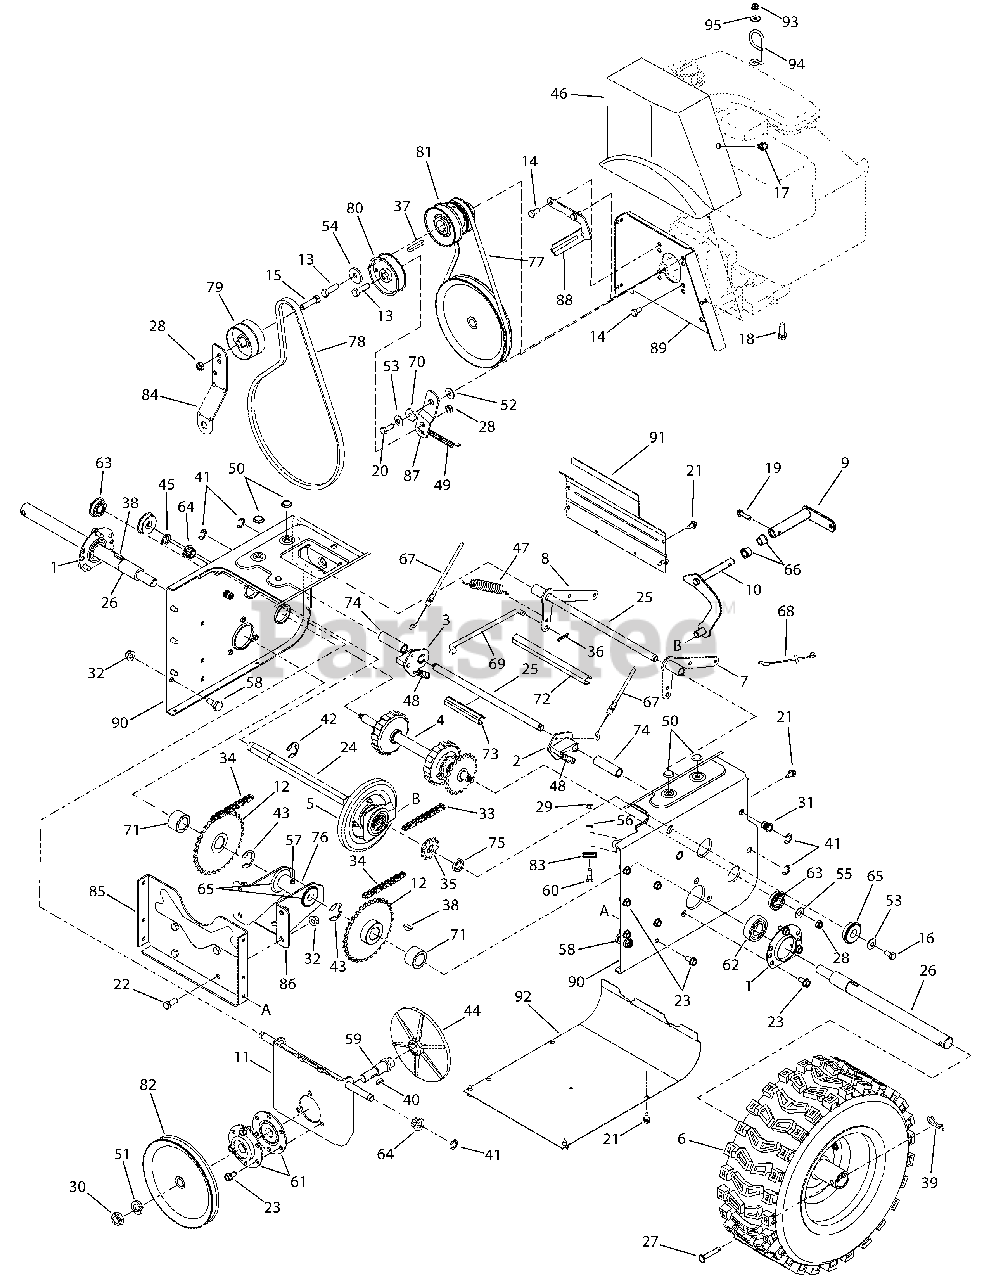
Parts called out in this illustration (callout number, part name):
1	Housing, Bearing
2	Dogg, Steering Drive, LH
3	Dogg, Steering Drive, RH
4	Shaft Assembly, Steering
5	Assembly, Friction Wheel
10	Rod Assembly, Shift
12	Sprocket, 32T
13	Screw, Hex Cap, 3/8-24 x 1.25 Gr8
14	Screw, Hex Cap, 5/16-24 x .625 Gr5
15	Screw, 3/8-24 x 1.50
16	Screw, Hex Cap Lock, 5/16-18 x .625 Gr5
17	Screw, Hex Tapp, 5/16-18 x .5
18	Screw, Hex Sems Tapp, 3/8-16 x 1.0
19	Screw, Hex, 1/4-20 x 1.00
20	Screw, Hex Lock, 5/16-24 x .875 Gr8
21	Screw, Hex Wash.
22	Screw, Hex Cap, 3/8-16
23	TT Screw, 5/16-18 x .750
24	Shaft, Hex Drive
25	Shaft, Actuator
26	Axle, Wheel
27	Pin, Clevis
28	Nut, Hex Insert Jam Lock
29	Nut, Hex, 1/4-28 GR5
30	Nut, Hx Insert Jam Lk
31	Nut, Insert 3/8-16
32	Nut, Hx Flnge Insert Lk
33	Chain, Endless, #41 x 36L
34	Chain, #420 x 40L
35	Sprocket, #41 x 10T
36	Pin, Internal Cotter
37	Key, Square, 1/4 x 1.5
38	Key, Woodruff
39	Pin, Internal Cotter
40	Key, Hi-Pro, 3/16 x 5/8
41	E-Ring
42	Ring, Retaining
43	Ring, Retainer
44	Plate, Drive
45	Nut, Speed
46	Cover, Belt
47	Spring, Extension
48	Spring, Extension
49	Spring, Extension, .375 x 3.18
51	Washer, Lock, 5/8
52	Washer, Flat, .349 x .879 x .063
53	Washer, Belleville, .34 x .872 x .06
54	Washer, Flat, .406 x 1.25 x .157 HT
55	Wash, .406 x .875 x .059
56	Washer, Lock, 1/4
57	Fitting, Lube, 3/16 Drive
58	Screw, Shldr., .498 x .34
59	Spindle, Drive Plate
60	Screw, Hex Shldr., 1/4-28
61	Ass’y, Bearing/Housing
62	Bearing, Self Aligning
63	Bearing, Ball
64	Bearing, Hex Flange
65	Bearing, Ball
66	Bush, Flg, .5 ID x .627 OD
67	Cable, Steering
68	Cable, Auger Idler
69	Rod, Drive Clutch
70	Spacer, Shoulder
71	Spcr., 1.0 ID x 1.50 OD
72	Spcr., .51 ID x 7.895 Lg.
73	Spcr., .51 ID x 3.66 Lg.
74	Spcr., .514 x .632 x 2.44
75	Spacer, .675 x 1.0 x .23
76	Spcr, .6725 x 1.125 x 2.48
77	V-Belt, 3/8 x 35.5
78	V-Belt, 1/2 x 44.0
79	Idler, Flat, 2.75 OD
80	Pulley, Flat Idler, 3.0 OD
81	Pulley, Dbl, 3.25 OD
82	Pulley, Drive
83	Roller, Cable
84	Brkt., Idler, Auger
87	Bracket, Idler, Drive
93	Nut, Flange Lock, 1/4-20 GrF
94	Guide, Control Cable
95	Washer, Flat, .28 x .74 x .063
